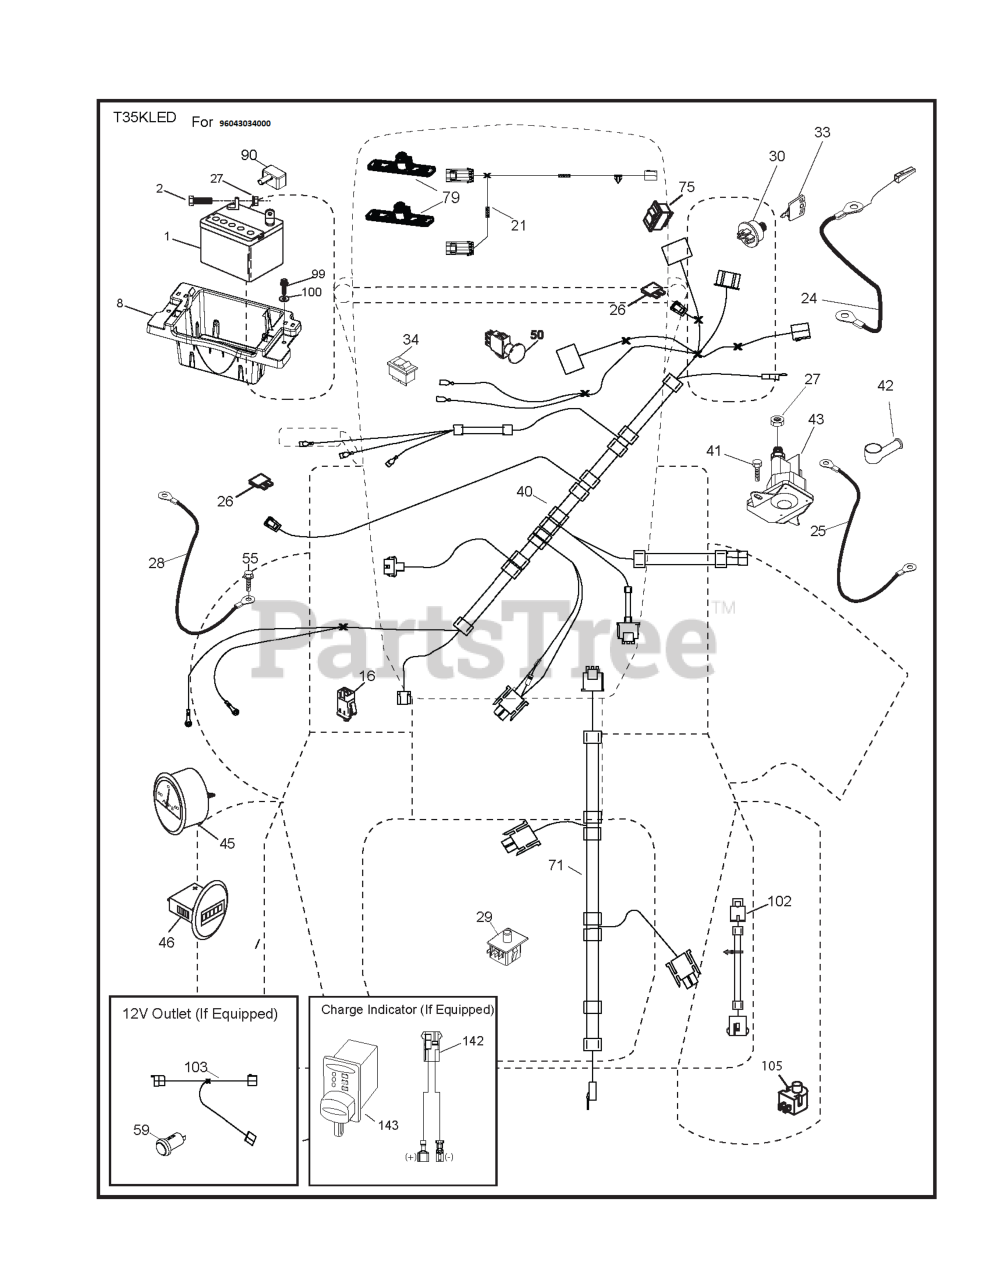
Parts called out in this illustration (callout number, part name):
1	BATTERY.DRY.30.AMP
2	BOLT.HEX.1/4.X.3/4.DICHROMATE
8	TRAY.BATTERY BOX.FRONT
16	SWITCH INTERLOOK PUSH-IN
24	CABLE.FRBATT.W/WIRE.8GA.8
25	CABLE.STARTER.8GA.17.5
26	FUSE 20AMP
28	CABLE.GROUND.21"BLK.8GA.90T
29	SWITCH.SEAT.DELTA.OPC.
30	SWITCH.IGN.DELTA.W.LGH.ROS
33	KEY.CHAIN.BLISTER.PACK.GEN.INT
40	HARNESS.DASH.EDIFF.RND.CHG
42	COVER.TERMINAL.RED
50	SWITCH.PTO.8TERMINAL.STD.BLK
55	BOLT.5/16-18UNCX3/4 W/SEMS.BLK
71	HARNESS.IGN.CHASSIS.TEX.DCKLOC
75	SWITCH.ON/OFF.(DIFF.LOCK)
90	ROD.BYPASS.VARIATOR.GEN2
99	SCREW HEXWSHR 1/4-20X3/4
102	HARNESS PIGTAIL PCH TEX ROS
103	HARNESS.PIGTAIL.12V.OUTLET.
105	REVERSE SWITCH
